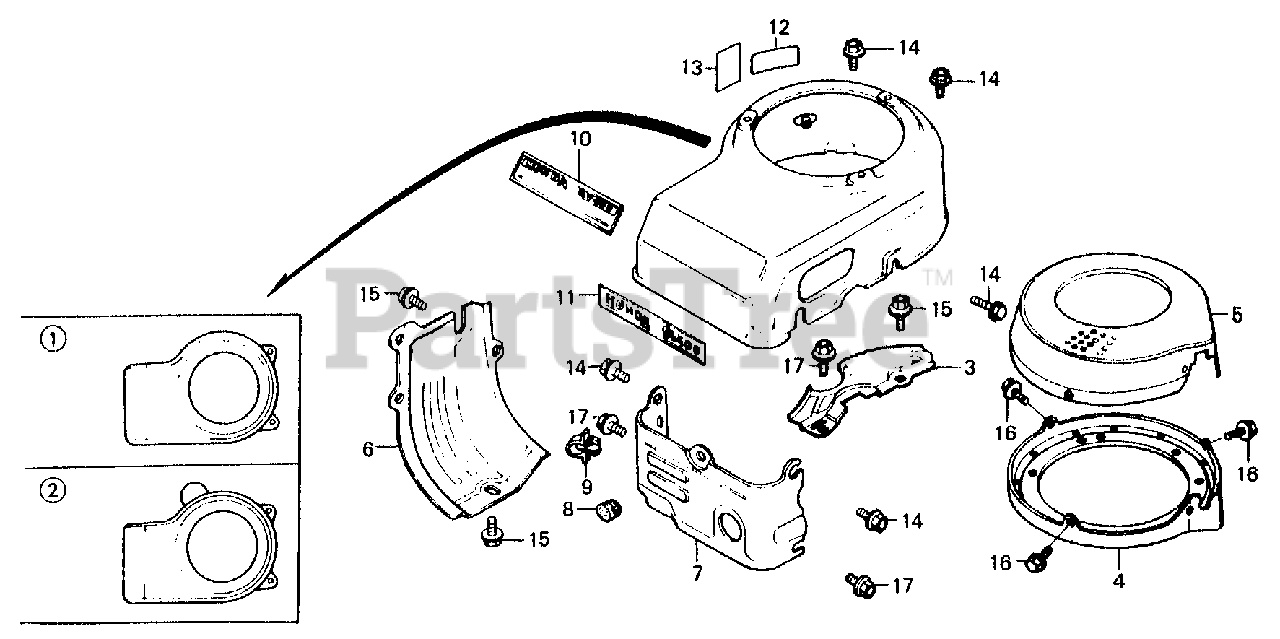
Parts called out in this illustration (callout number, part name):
2	COVER, FAN *R8* (BRIGHT RED)
3	PLATE, SIDE
4	BASE, LAWN COVER
5	COVER, LAWN
6	SHROUD
7	COVER, TOP
8	GROMMET, TOP COVER
9	CLIP, IGNITION WIRE (8MM)
10	EMBLEM (HP)
13	MARK, OIL CAUTION
14	BOLT, FLANGE (6X12) (CT200)
15	BOLT, FLANGE (6X16)
16	BOLT, FLANGE (6X8)
17	BOLT, FLANGE (6X12)
